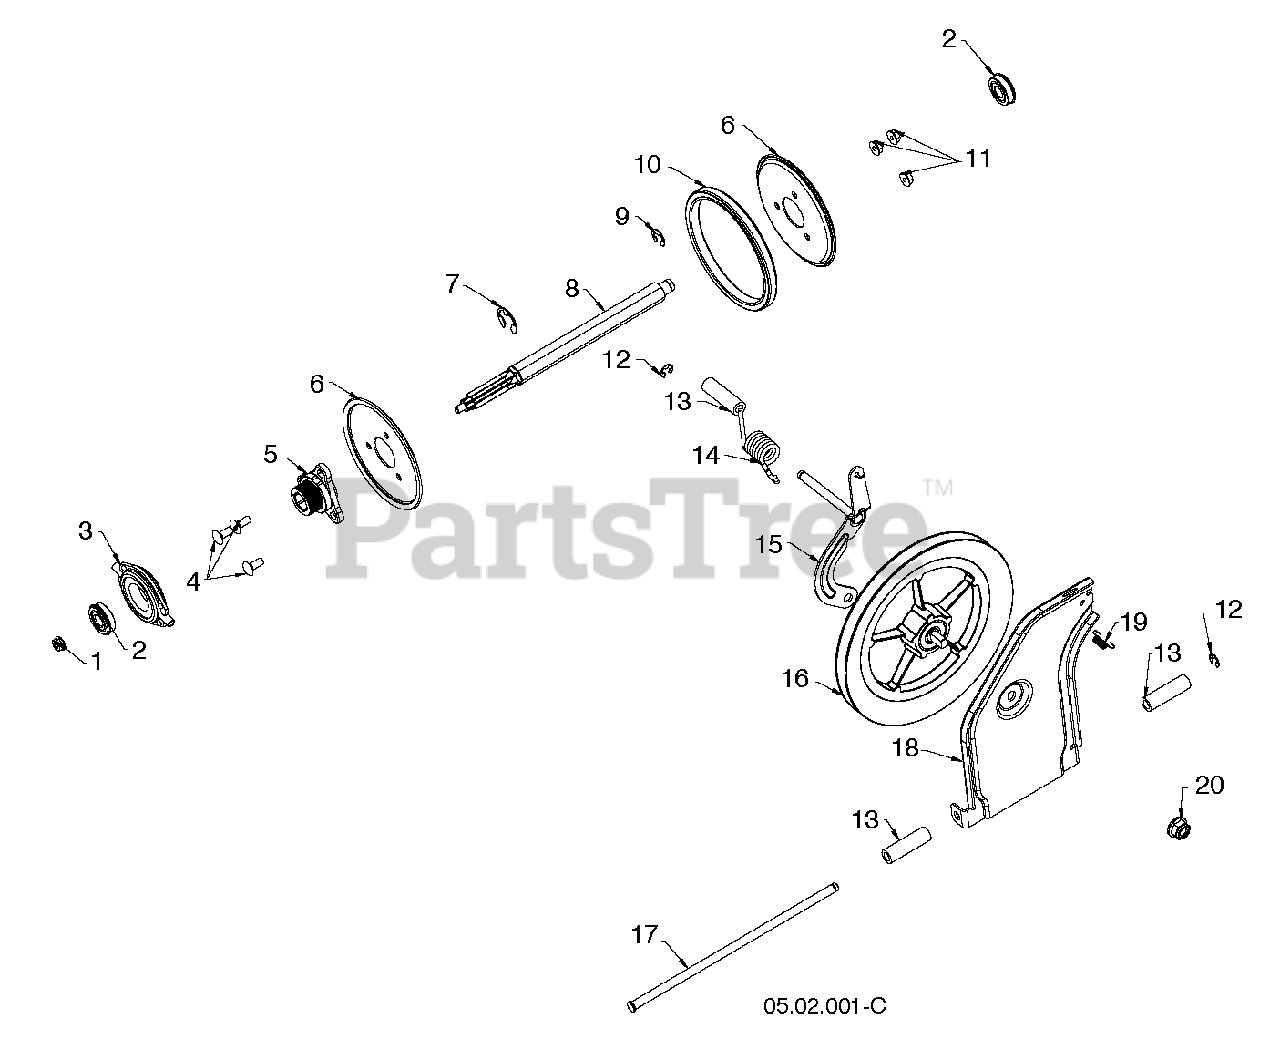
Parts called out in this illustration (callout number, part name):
1	NUT.HEX.FLANGE.LOCK.5/16-18
2	BEARING 9/16 ID. SNR
3	TRUNNION BEARING ASSY
4	BOLT.CARR.SQNK.5/16-18UNC.X3/4
5	HUB.RUBBER.WHEEL
6	PLATE.RUBBER.WHEEL.BLACK
8	SHAFT SHAFT,7T REDUCTION
9	RING RING, RETAINING RING (996
10	RING RUBBER
11	NUT.LOCK.5/16-18
12	E-RING LT
13	SPACER YOKE, TORSION SPRING
14	SPRING TORSION DRIVE
15	BRACKET YOKE WELDMENT_MS 479
16	PULLEY.FRICTION.DISC.COMBO
17	ROD.TIP.PLATE
18	PLATE SWING FRICTION PULL_MS
19	SPRING LATCH
20	NUT, 1/2-13 HEX FLG NYLOC ZD
